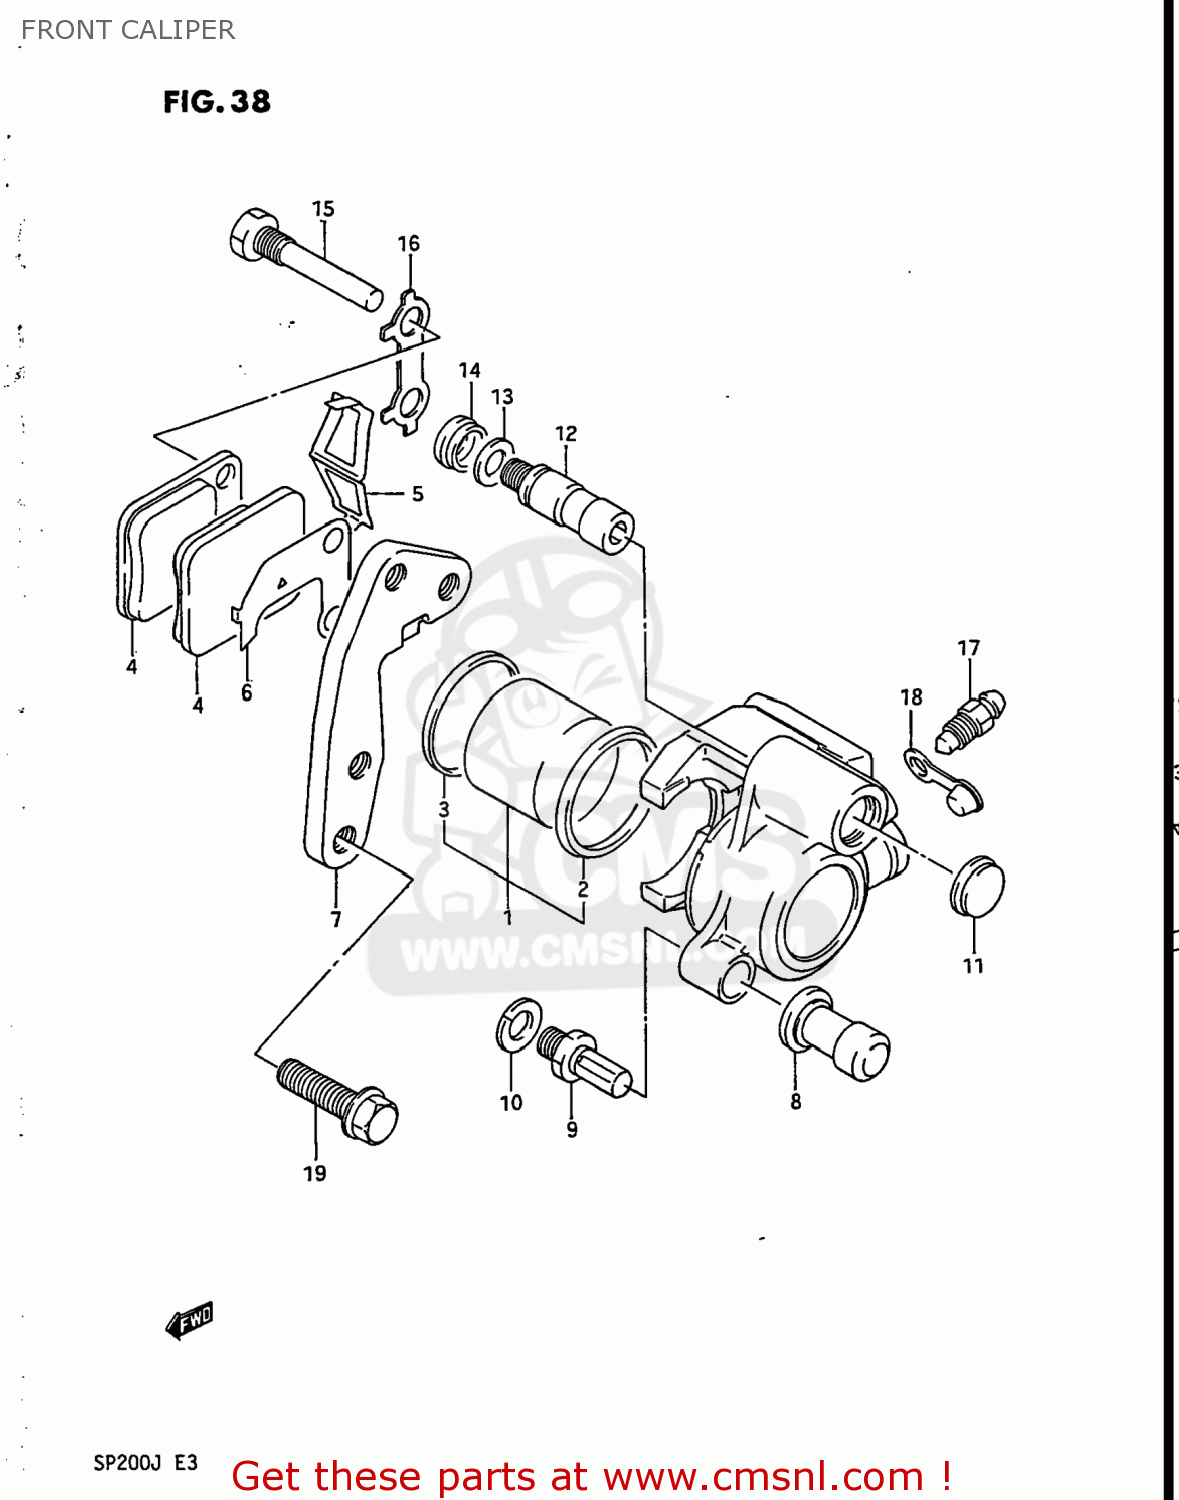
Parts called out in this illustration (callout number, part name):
1	PISTON SET,CALIPERS
2	SEAL,PISTON
3	BOOT,PISTON
4	PAD
5	SPRING,PAD
6	SHIM
7	BRACKET
8	BOOT
9	BOLT,PIN
10	WASHER,WAVE
11	DUST SEAL
12	PIN,SLIDE
13	SPRING,FRICTION
14	BOOT,PIN
15	PIN,HANGER
16	WASHER
17	BLEEDER
18	CAP,BLEEDER
19	BOLT 8X30
